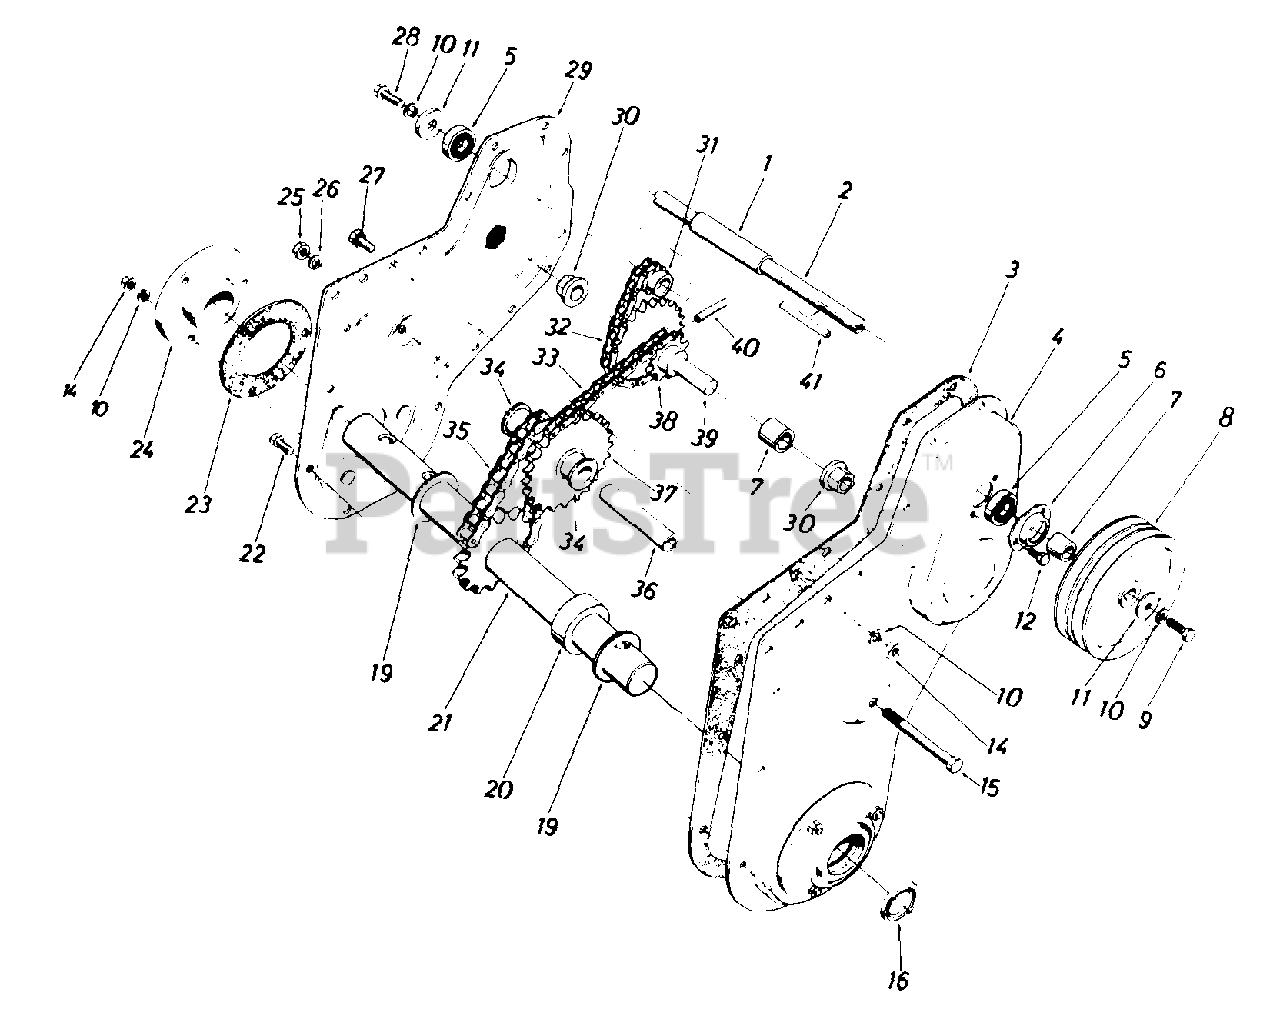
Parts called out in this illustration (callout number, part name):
1	Spacer .657 I.D. x .78 O.D. x 2.19
2	Jack Shaft
3	Gasket for Housing
4	Housing Half - L.H.
5	Ball Bearing .625 I.D. x 1.375 O.D.
6	Bearing Housing
7	Spacer .625 I.D. x .88 O.D. x 1.035
8	Chain Case Pulley 6.00" Dia.
9	Hex Bolt 5/16-18 x 1.00" Lg. Special
10	L-Wash. 5/16" Scr.
11	Fl-Wash. 5/16 I.D. x 1.125 O.D. x .125
12	Hex Self-Tap Scr. 1/4-20 x .50" Lg.
14	Hex Nut 5/16-18 Thd.
15	Hex Bolt 3/8-16 x 3.25" Lg.
16	Oil Seal 1" I.D. x 1.357 O.D.
19	Fl-Wash. 1.0" I.D. x 1.62 O.D. x .090
20	Spacer 1.0" l.D. x 2.0" O.D. x .68
21	Tine Shaft Ass'y.
22	Hex Self-Tap Scr. 1/4-20 x .50" Lg.
23	Gasket for Bearing Hsg.
24	Bearing Housing Ass'y.
25	Hex Nut 3/8-16 Thd.
26	L-Wash. 3/8" Scr.
27	Hex Sems Bolt 5/16-18 x 1.00" Lg.
28	Hex Bolt 5/16-18 x .62" Lg. Special
29	Housing Half - R.H.
30	Hex Flanged Bearing .630 I.D.
31	Sprocket 10 Teeth x .500 Pitch
32	#41 Chain 1/2" Pitch x 34 Links - Endless
33	#420 Chain 1/2" Pitch x 48 Links - Endless
34	Flange Bearing .626 I.D.
35	#50 Chain 5/8" Pitch x 28 Links - Endless
36	Sprocket Shaft
37	Sprocket Bearing Sleeve Ass'y.
38	Sprocket Sleeve Ass'y.
39	Sprocket Shaft
40	Spring Pin Spiral 1/4" Dia. x 1.5" Lg.
41	Sq. Key 3/16 x 1.50" Lg.
